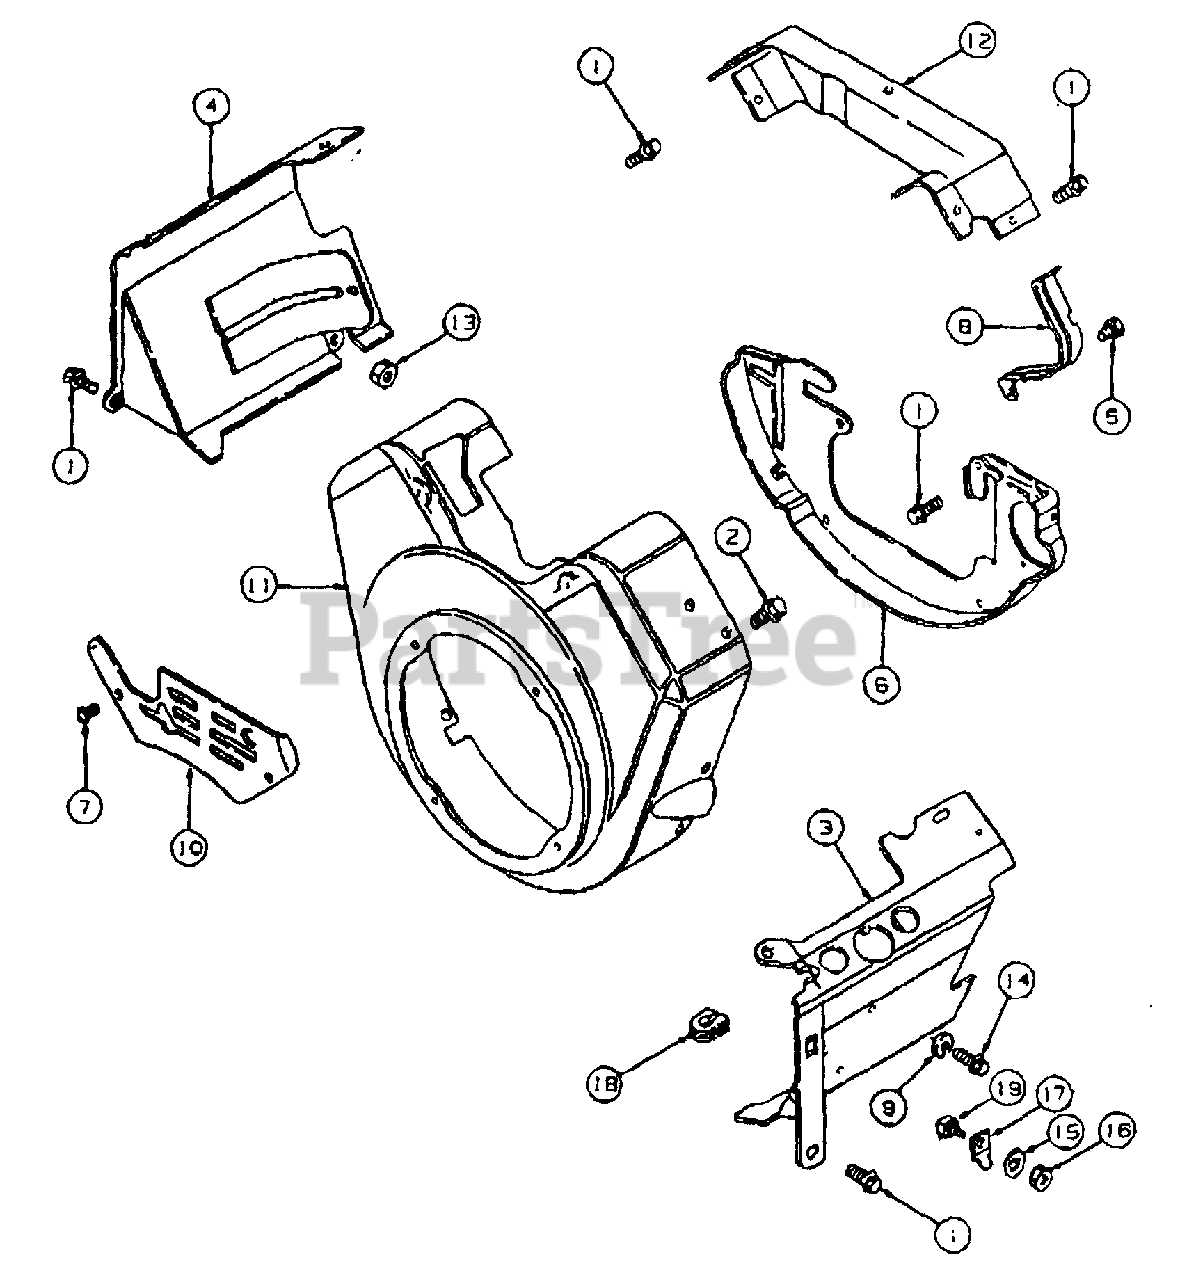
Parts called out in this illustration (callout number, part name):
1	Screw, Sems
2	Screw, Sems
3	Cover (Cylinder #1)
4	Cover (Cylinder #2)
5	Screw, Sems
6	Plate, Back
7	Screw, Sems
9	Washer, Lock
10	Cover, Carburator
11	Housing, Blower
12	Cover, Valley Extension
13	Nut, Hex
14	Screw, Mtg
15	Washer, Lock, Internal Tooth
17	Terminal, Ground
18	Grommet, Cable
19	Insulator Assy,
